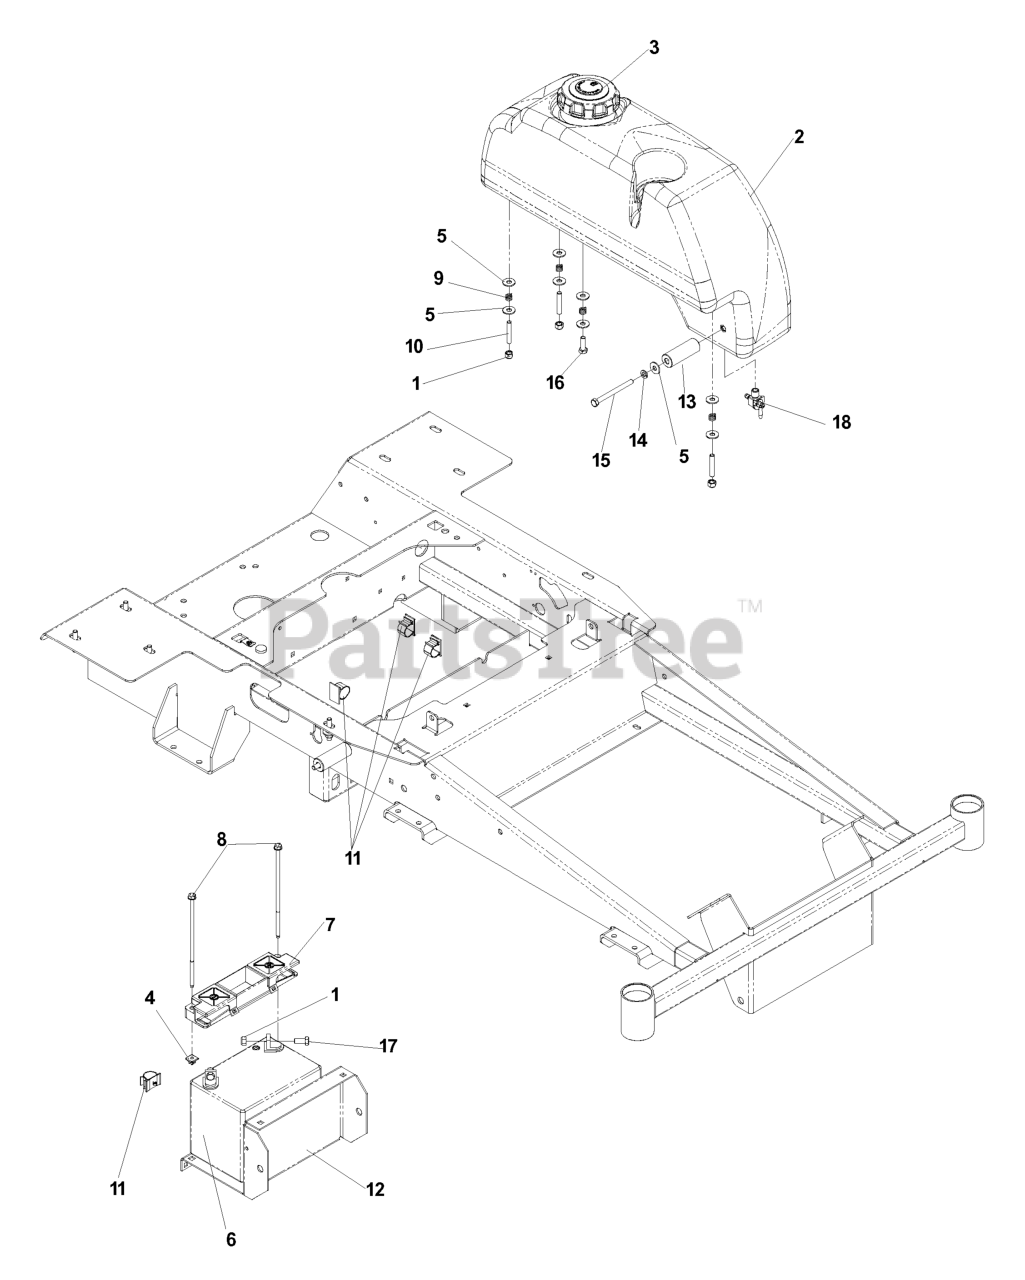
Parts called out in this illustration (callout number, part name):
1	NUT 5/16 NYLOC
2	LEFT TANK W/CUP HOLDER
3	FUEL CAP ANTI-SPLASH
4	PUSH NUT-NYLON
5	WASHER 5/16 FLAT
6	BATTERY, 12 V 330 AMP
7	BATTERY HOLD DOWN
8	BOLT - 1/4-20 X 7.5
10	STUD, 5/16C
11	PUSH-MOUNT WIRE CLIP
12	BATTERY TRAY
13	TANK SPACER
14	WASHER.LOCK.HVY.HLCL.SPR.5/16
15	HCS, 5/16-18 X 3 1/2, GR5
16	HCS 5/16C X 1
17	HCS 5/16C X 3/4
18	FUEL VALVE
